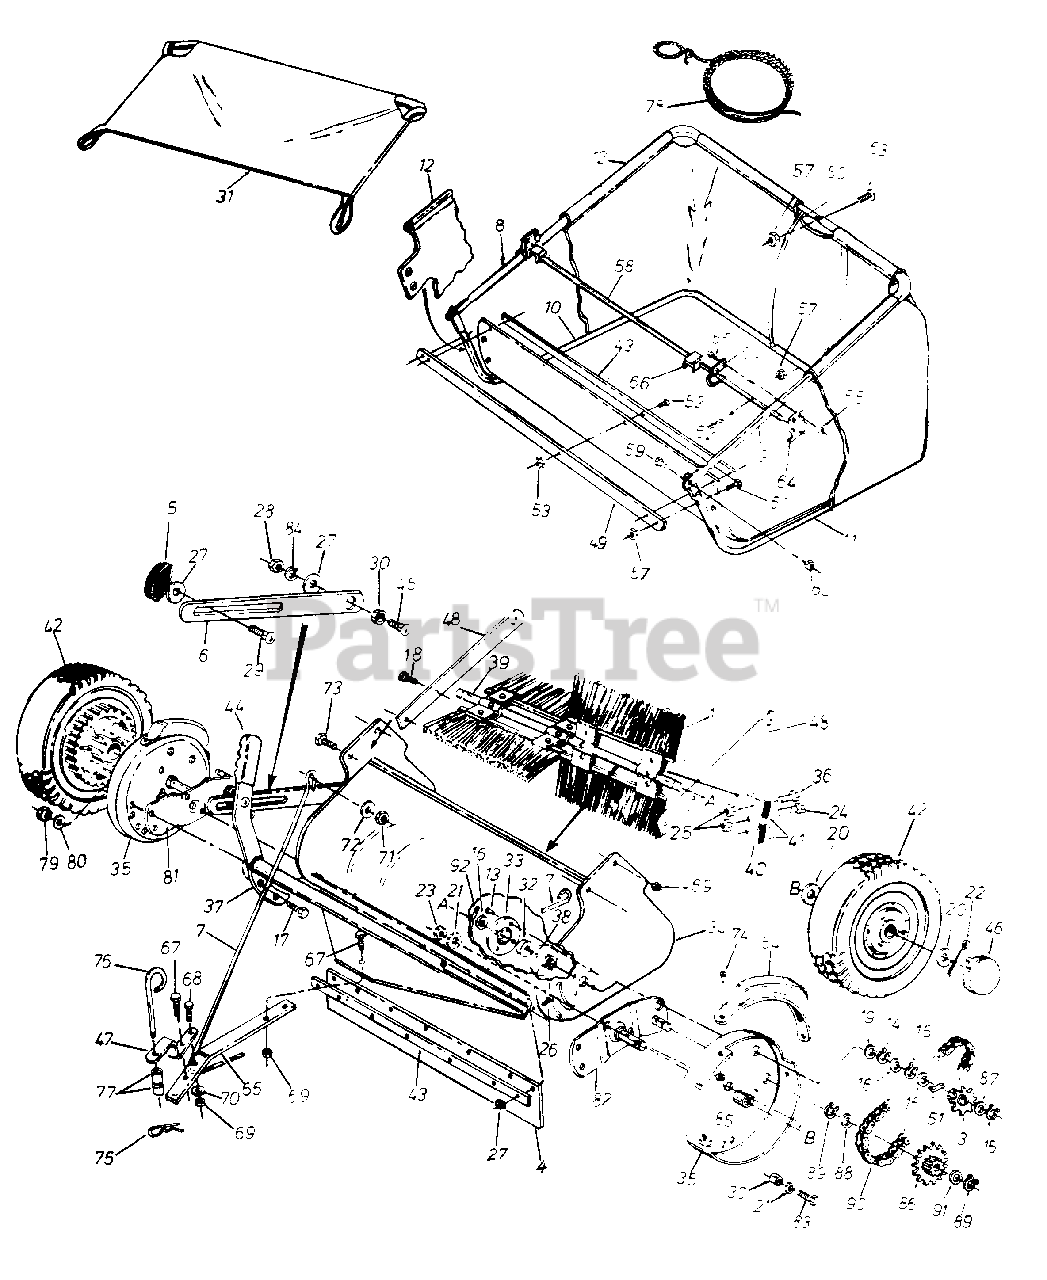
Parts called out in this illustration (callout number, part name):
3	Sprocket-Ratcher L.H.
5	Height Adjustment Knob
6	Height Adjustment Strap
7	Brace Rod
8	Upper Hopper Tube-R.H.
9	Upper Hopper Tube-L.H.
10	Lower Hopper Tube-R.H.
11	Lower Hopper Tube-L.H.
12	Hopper Bag
13	Rivet
14	Retaining Ring-3/4"
15	Retaining Ring .594 I.D.
16	Fl.-Washer (Shim) .596 x 1.125 x .025
17	Hex Bolt 5/16-18 x 3/4" Lg
18	Hex Bolt 3/8-16 x 3/4" Lg. (Gr. 5)
19	Fl.-Washer .783 x 1.125 x .025
20	Fl.-Washer .51 x .990 x .020
21	Washer 3/8" Std.
22	Cotter Pin 1/8" Dia. x 3/4" - Lg.
23	Hex Lock Nut 3/8-243 Thd.
24	Hex Bolt 1/4-20 x 1" Lg.
25	Hex Lock Nut 1/4-20 Thd.
26	Truss. Slotted Hd. Scr. #10-32 x 1/2" Lg.
27	Washer, 5/16" Std.
28	Hex Nut 5/6-18 Thd.
29	Carriage Bolt 5/16-18 x 3/4" Lg.
30	Bushing Spacer
31	Wind Screen
32	Ball Bearing .5915" I.D.
33	Bearing Retainer
34	Sweeper Housing Ass'y.
35	Dust Cover
36	Hex Bolt 1/4-20 x 3/4" Lg (Gr. 5)
37	Height Adjustment Tube Ass'y.
38	Brush Bushing Ass'y.
39	Brush Shaft
40	Brush Retainer (Double)
41	Brush Retainer (Single)
42	Wheel Ass'y. Comp.
43	Skirt Retainer
45	Carriage Bolt 5/16-18 x 3/4" Lg.
46	Hub Cap
47	Hitch Bracket
48	Bag Mount Arm
49	Bag Frame Strap
50	Wire Support
51	Pawl (HT)
52	Truss Hd. Slotted Scr. #10-32 x 5/8" Lg.
53	Hex Lock Nut #10-32 Thd.
54	Chain Shield
55	Hex Lock Nut 5/16-18 Thd.
56	Hex Bolt 5/16-18 x 3/4".
57	Hex Lock Nut 1/4-20 Thd.
58	Hopper Bag Pivot Rod
59	Hex Bolt 3/8-16 x 3/4"
60	Hex Lock Nut 3/8-16 Thd.
61	Hex Bolt 1/4-20 x 1-1/4" Lg.
62	Cotter Pin 1/8" Dia. x 3/4" Lg.
63	Curved Hd. Bolt 1/4-20 x 1" Lg.
64	Hopper Mount Clamp
65	Hitch Bar
66	Bag Retainer Clevis
67	Hex Bolt 3/8-16 x 1" Lg. (Gr. 5)
68	Hex Bolt 3/8-16 x 1-1/2" Lg
69	Hex Lock Nut 3/8-16 Thd.
70	Fl.-Washer 17/32 x 1-1/2"
71	Hex Lock Nut 3/8-16 Thd.
72	Fl.-Washer 3/8" Std.
73	Hex Bolt 3/8-16 x 1-1/4" Lg.
75	Hairpin Cotter 5/32
76	Hitch Pin
77	Hitch Adjustment Tubes
78	Hopper Rope
79	Hex Lock Nut 5/16-18 Thd.
80	Washer, Std. 5/16" S.A.E.
81	Wheel Hanger Ass'y-R.H.
82	Wheel Hanger Ass'y-L.H.
83	Hex Bolt 3/8-24 x 1" Lg.
84	Lock Washer 5/16" I.D.
86	Sprocket Gear
87	Washer, Flat .596 x .859 x .025
88	Washer .51 x .990 x .02
89	Retaining Ring - 1/2"
90	Roller Chain
91	Washer .515 x .75 x .026
92	Spring Pin 3/16 x 1"
